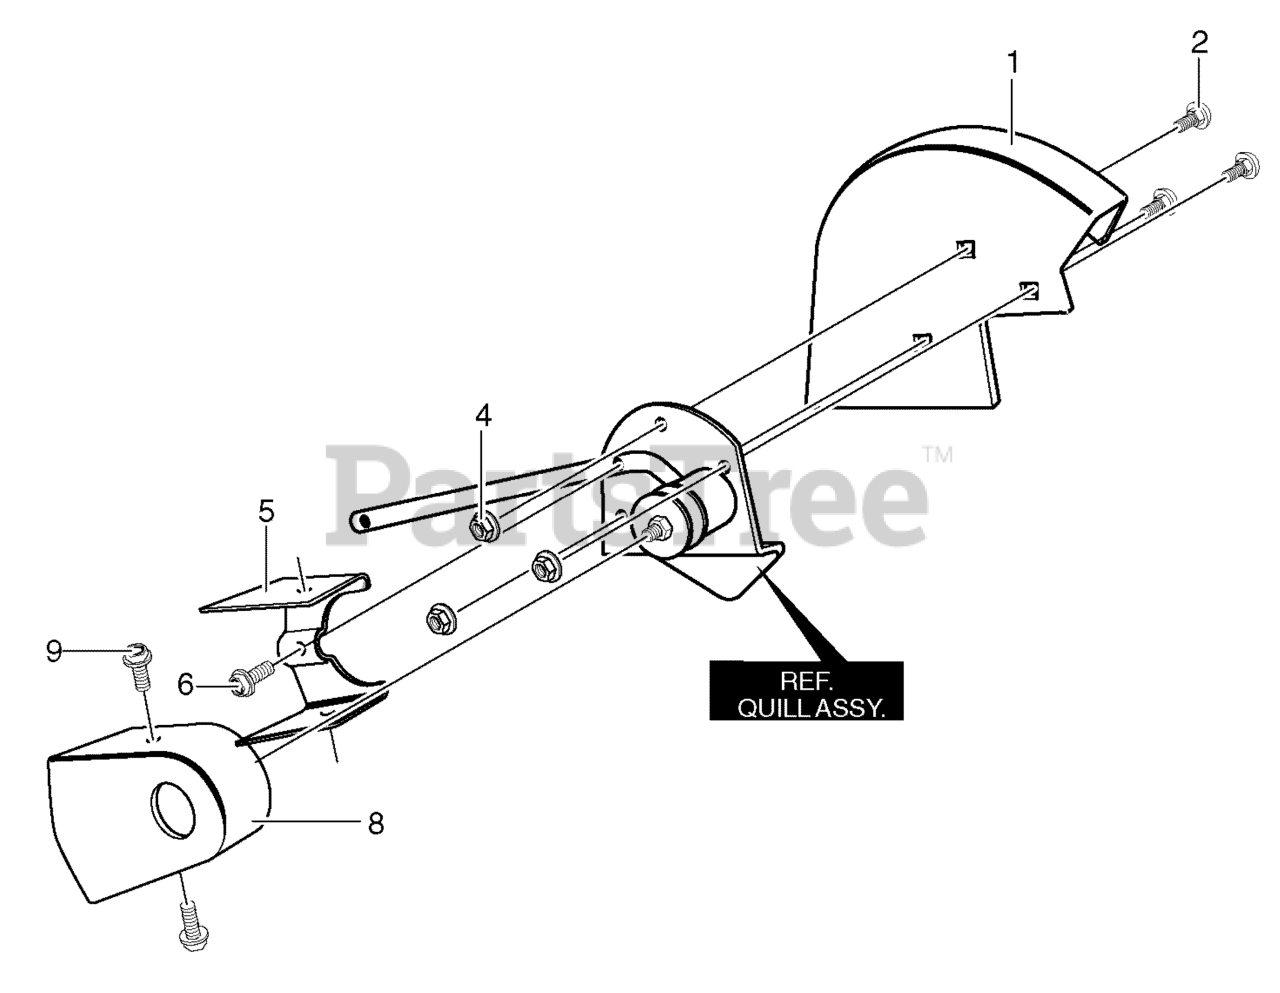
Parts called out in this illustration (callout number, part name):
1	Blade Guard
2	Bolt, Carriage 5/16-18x.63
4	Nut, 5/16-18
5	Guide, Belt Front
6	Screw, 1/4-20x.50
8	Cover, Quill Pulley
9	Screw, 10-16x.50
